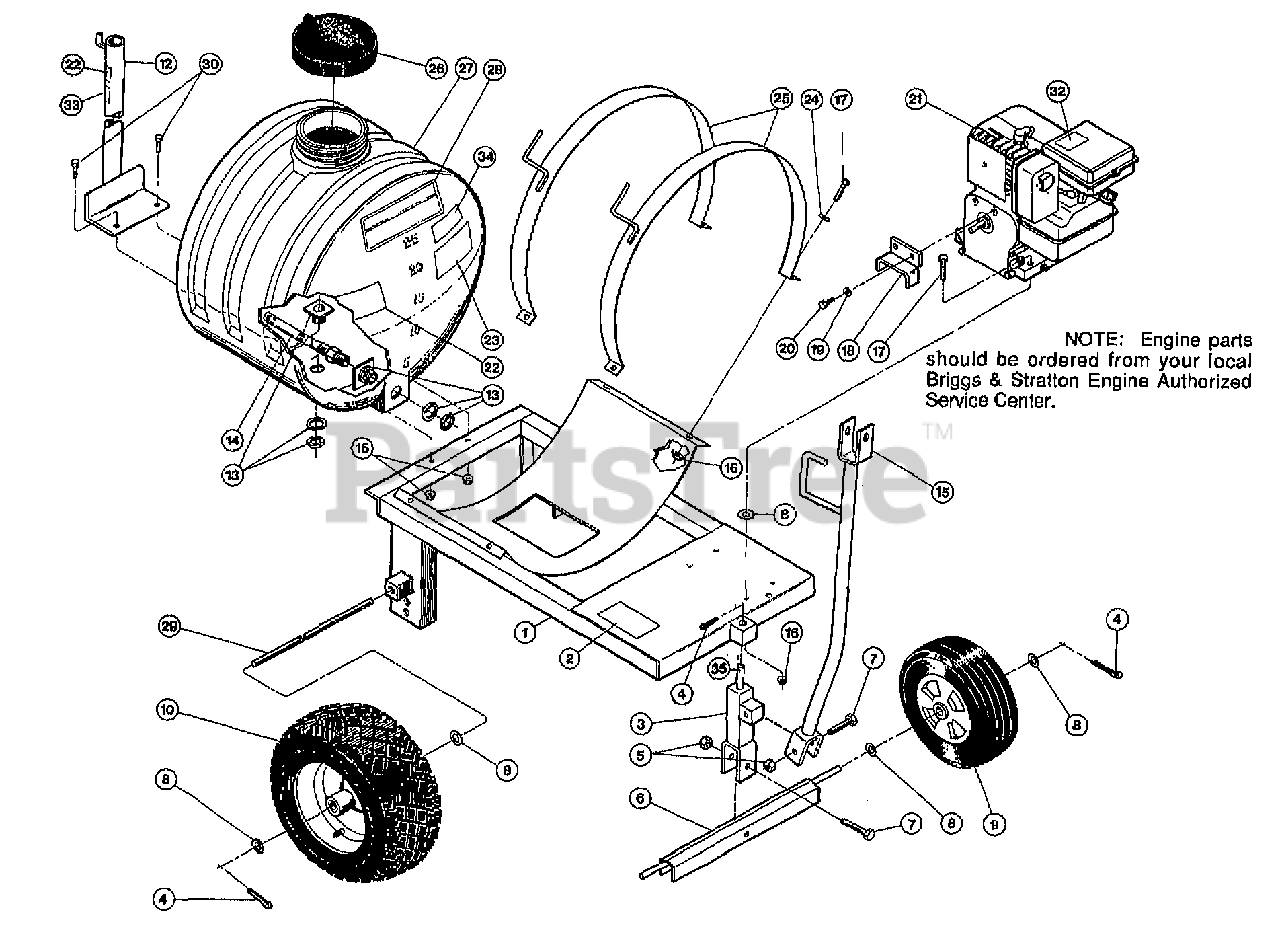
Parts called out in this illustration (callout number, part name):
1	ASSM-UNDERCARRIAGE W21401501
2	DECAL-SAVE
3	ASSM-AXLE PIVOT FRONT
4	PIN-COTTER .120X1.25 ZP
5	NUT-LOCK
6	ASSM-FRONT AXLE SPRAYER
7	SCR-HH 5/8-11X2.25 G5 ZP
8	WASHER-1.305X.649X.098 ZP
9	ASSM-WHEEL/TIRE 10X4
10	ASSM-WHEEL/TIRE 15X6
12	MAST-BOOM W/DECALS W20201502
13	ASSM-BULK HEAD W21254002
14	AGITATOR-JET W33710019
15	HANDLE-TOW BAR
16	NUT-HFLK 5/16-18 ZP
17	SCR-HFLK 5/16-18X1.50
18	COVER-SHAFT W/A
19	WASHER-LK .312 ZP
20	SCR-HH 5/16-24X.50
21	ENGINE-3.5HP
22	DECAL-DANGER AVOID W2045146
23	DECAL-ENG SPEED W2045149
24	WASHER-FLAT 5/16 SAE
25	BAND-TANK
26	CAP-TANK W21254503
27	ASSM-TANK 25 GAL W/DECALS
28	DECAL-25GAL SPRAY W2045165
29	AXLE-REAR 25GAL SPRAYER
30	SCR-HH 5/16-18X1.0 G5 ZP
32	DECAL-CAUTION HOT SURFACE
33	DECAL-40PSI CAUTION W2045147
34	DECAL-DAVIOD SPRAY W0245106
35	SHAFT-PIVOT W20051003P
